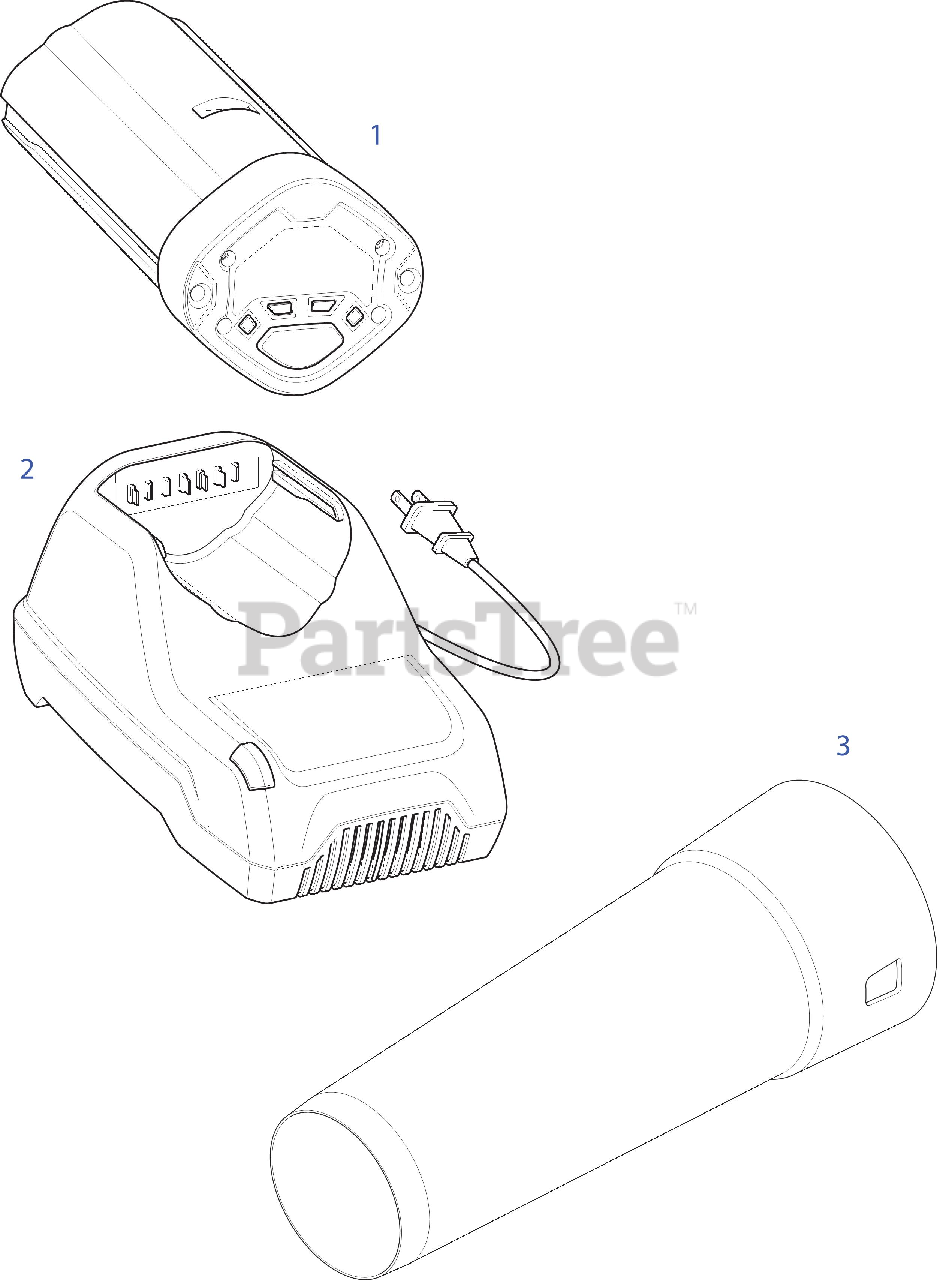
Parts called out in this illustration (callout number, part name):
1	4Ah Lithium-Ion Battery*
2	Charger*
3	Blower Tube
